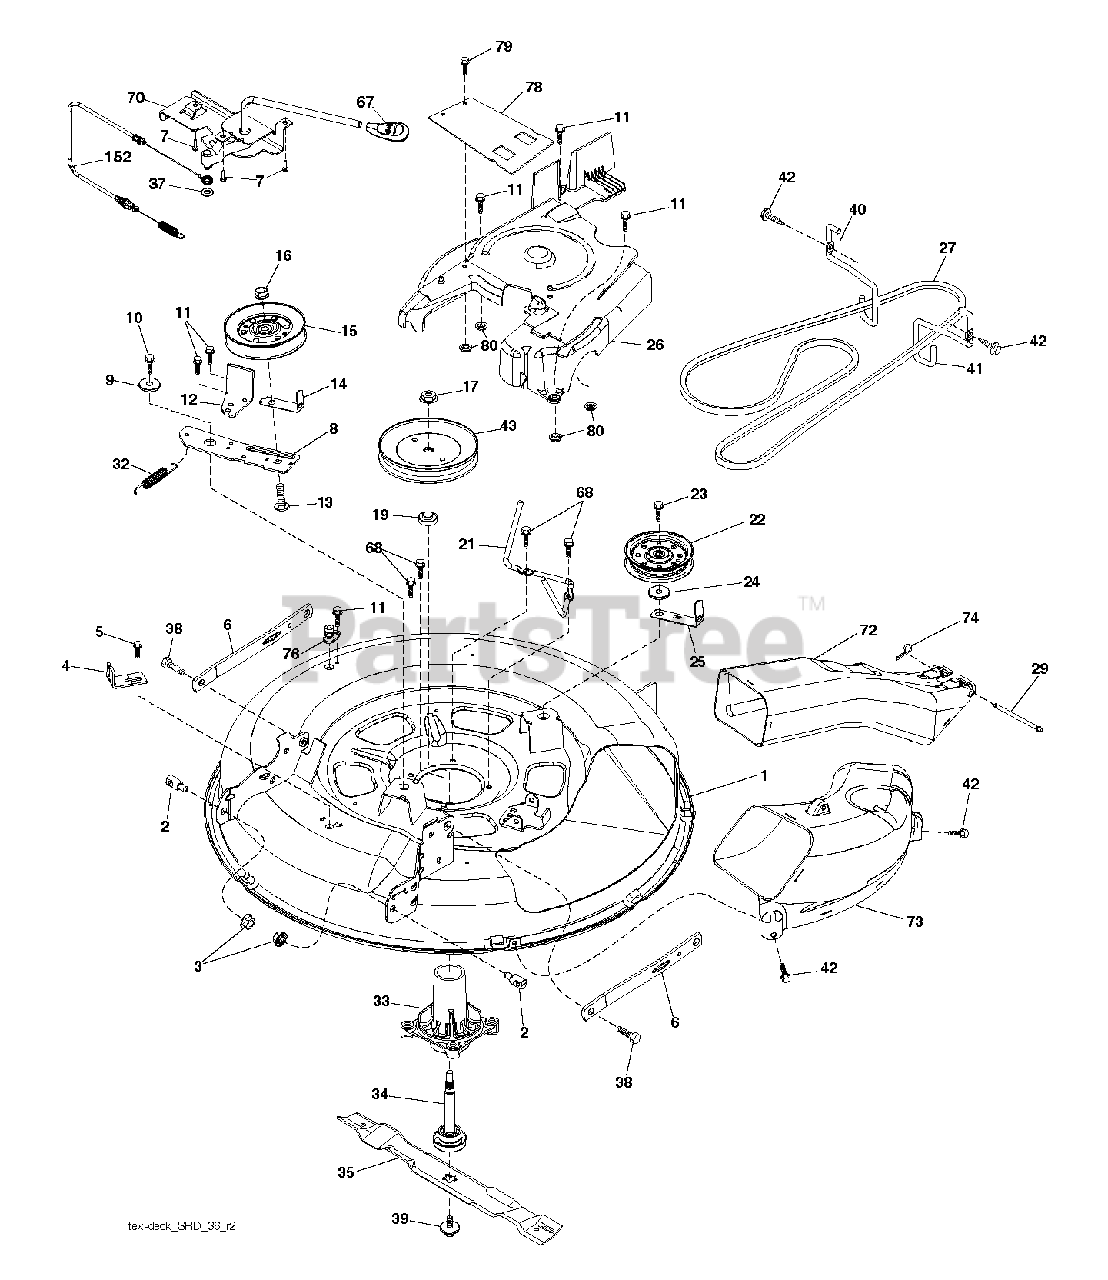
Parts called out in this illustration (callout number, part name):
1	DECK.WELDMENT.PNT.30"SRD
2	STUD.FASTNER.W/ANTI-ROTATE
3	NUT LOCK HEX FLANGE 5/16-18
4	BRACKET.CLUTCH.CABLE
5	BOLT.5/16HEX.WHS.HD
6	ARMS.SUSP.MOWER.REAR.SRD
7	SCREW.#10 X 0.750.BOS
8	ARM.IDLER.30"SRD
9	SPACER.RETAINER
10	SCREW 3/8-16X1
11	SCREW.1/4-20X5/8
12	RP ARM.BRAKE.MOWER.38"LH.TEX
13	BOLT.3/8-16X1.50
14	KEEPER, BELT IDLER
15	PULLEY.IDLER.4.25
16	NUT LOCK FLG 3/8-16 UNC
17	NUT.FLANGE.LOCK.TOP
19	BEARING.MANDREL.TOP.EXTENDED
21	KEEPER.BELT.MANDREL.30"
22	PULLEY.IDLER.FLAT.46.PR.DR.
23	SCREW LT
24	WASHER
25	KEEPER.BELT.30"SRD
26	COVER.ASM.MANDREL.30"
27	V-BELT.DRIVE.MOWER.30"
29	PIN.HINGE.30".SRD
32	SPRING RETURN
33	HOUSING.MANDREL.4PT.
34	SHAFT ASM.MNDRL.N/GREASEABLE
35	BLADE.MOWER.BAGGING.30"
37	WASHER
38	BOLT.SHOULDER
39	SCREW.SEMS.7/16-20X1.HEX.HEAD
40	KEEPER.BELT.ENGINE.LH.LT.SRD
41	KEEPER.BELT.ENGINE.RH.LT.SRD
42	SCREW, 3/8-16X3/4
43	PULLEY, MANDREL 6.5 PD
67	HANDLE.CLUTCH.CABLE.LT
68	BOLT.HEX.WASHR.HED.313-18X1.19
70	CLUTCH.ASM.MANUAL.LT.PRED
72	CHUTE.UPPER.SRD.30R"
73	CHUTE.LOWER.SRD.30R"
74	Retainer Spring
76	PORT.WASHOUT
78	GUARD ARM CLUTCH
79	SCREW.HI-LO.CONSOLE
80	PALNUT 1/4
152	CABLE.CLUTCH.MANUAL.
